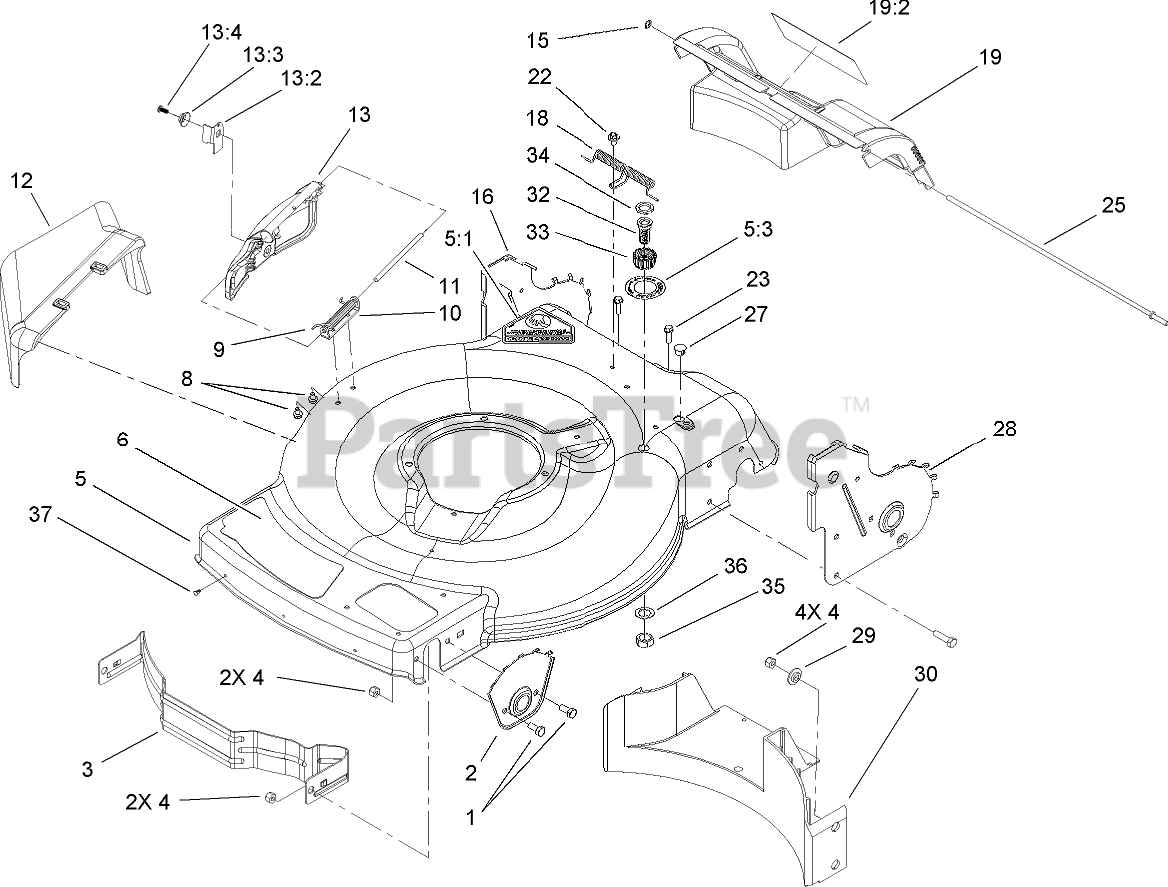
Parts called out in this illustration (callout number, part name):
1	SCREW-HH
2	Plate-HOC, Front
3	Baffle-Front
4	NUT-LOCK, NI
5	HOUSING ASM
5:1	DECAL-DANGER
5:3	DECAL-PORT, WASHOUT
6	DECAL-DECK
8	SCREW-HWH
9	SPRING-TORSION
10	BRACKET-COVER
11	ROD-COVER
12	CHUTE-DISCHARGE, SIDE
13	DISCHARGE DOOR ASM
13:2	LATCH-DOOR
13:3	CAP-DOOR
13:4	SCREW-PLASTITE
15	NUT-PUSH
16	11 INCH RH HOC PLATE ASM
18	Spring-Door, Rear
19	REAR DOOR ASM
19:2	DECAL-WARNING
22	SCREW AND WASHER ASM
23	SCREW-HWH
25	Rod-Pivot, Rear Door
27	Plug-Dome
28	11 INCH LH HOC PLATE ASM
29	Washer-Stepped
30	Baffle-Rear
32	PORT-WASHOUT
33	COUPLING-HOSE, WASHOUT PORT
34	WASHER-SEAL, WASHOUT PORT
35	NUT-JAM
36	WASHER-TOOTH, INTERNAL
37	PLUG-ARROW
